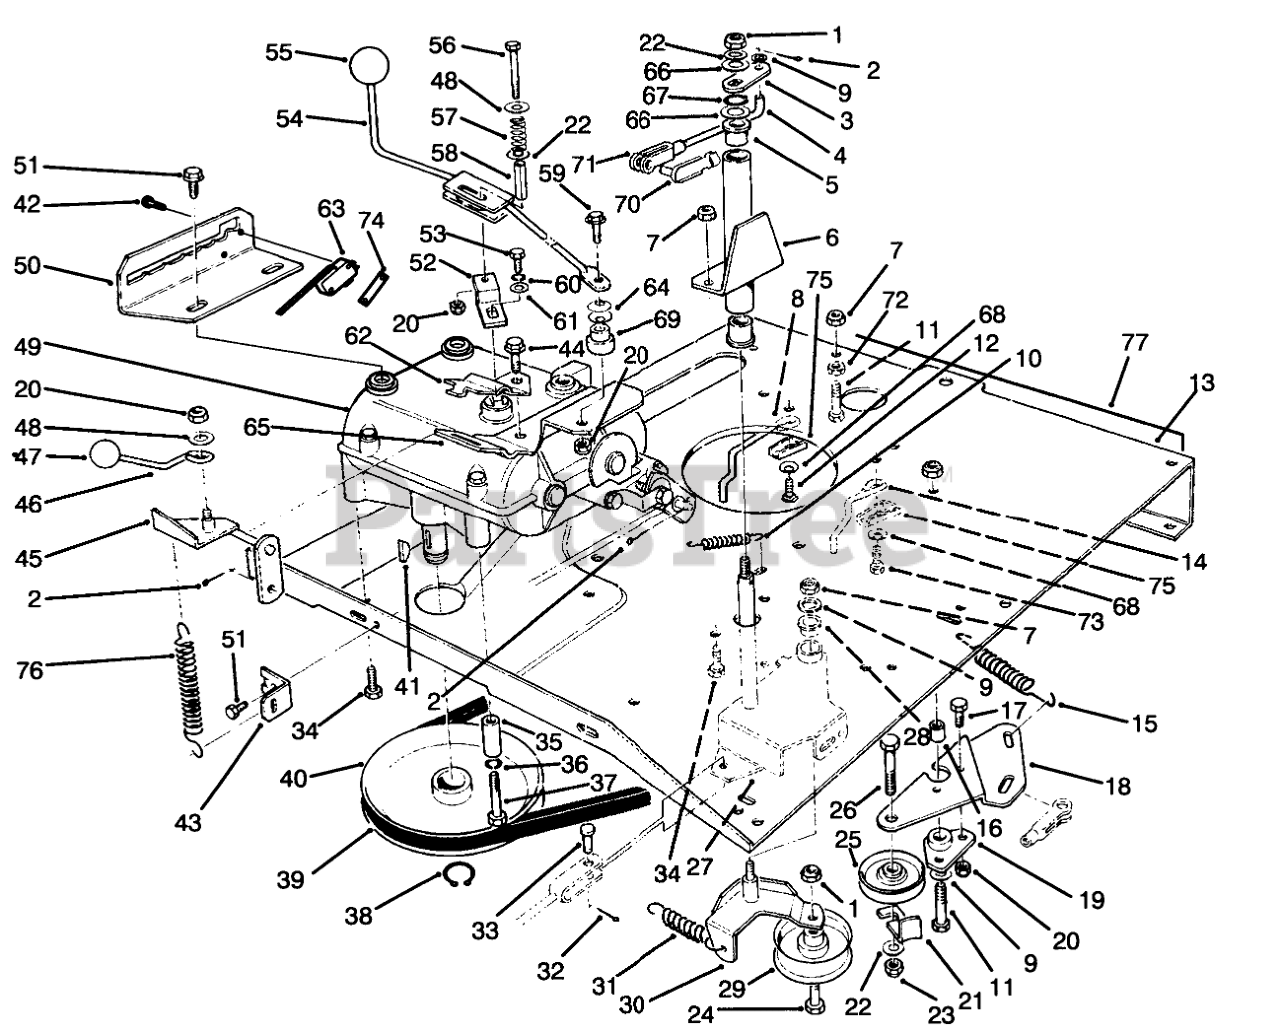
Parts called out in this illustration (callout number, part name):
1	NUT-LOCK, NI
2	PIN-COTTER
3	BRKT-DECK ENGAGE BLK
4	LINK-DECK ENGAGE
5	Bushing Tube W.A.-Pivot (Incl. Ref. #5)
6	IDLER PIVOT TUBE WA (RED)
7	NUT-LOCK, NI
8	ENG BELT GUIDE R.
9	WASHER-PLAIN
10	SPRING-RETURN, BRAKE
11	SCREW-HH
12	BOLT-CARR
13	Plate-Engine
14	GUIDE-ENG. BELT L.
15	SPRING-TRACTION
16	SPACER-PIVOT
17	SCREW-HH
18	PLT-IDLER MTG
19	MOUNT-TRACTION PIVOT
20	NUT-LOCK, NI
21	RETAINER-BELT
22	WASHER-FLAT
23	NUT-LOCK, NI
24	SCREW-HH
25	PULLEY-IDLER
26	SCREW-HH
27	Bracket-Arm, Idler (Incl. Ref. #28)
28	BUSHING-FLANGE
29	PULLEY-IDLER
30	IDLER MTG PLT WA (BLACK)
31	SPRING-IDLER
32	SCREW-HSH
33	PIN-CLEVIS
34	SCREW-HH
35	GUIDE-BELT
36	WASHER-LOCK
37	SCREW-HH
38	RING-SNAP, EXTERNAL
39	67BELT, TRACTION DRIVE
40	PULLEY
41	KEY-WOODRUFF
42	SCREW-HH
43	BRKT-SPRING MT
44	SCREW-HWHTF
45	DECK ENGAGE LEVER WA (BLACK)
46	ROD-ENGAGE
47	KNOB-CONTROL
48	WASHER-FLAT
49	TRANSMISSION
50	Gate-Shift
51	SCREW-HWHTF
52	LEVER-SHIFT
53	SCREW-HH
54	SHIFT LEVER WA (BLACK)
56	SCREW-HH
57	SPRING-COMPRESSION
58	SPACER-SPLIT
59	SCREW-HH
60	WASHER-LOCK
61	WASHER-FLAT
62	BRKT-DECK ENG UPPER
63	SWITCH-MICRO
64	WASHER-BELLEVILLE
65	BRKT-DECK ENG. SHIFTER
66	WASHER
67	RING-RETAINING
68	WASHER-BELLEVILLE
69	SPACER-PIVOT
70	CLEVIS PIN ASM
71	CLEVIS-ADJ
72	NUT-JAM
73	SCREW-FLOW, TAPTITE
74	NUT-SPEED
75	ANCHOR-GUIDE, BELT
76	SPRING-DOOR
77	DECAL - REAR FRAME TORO
